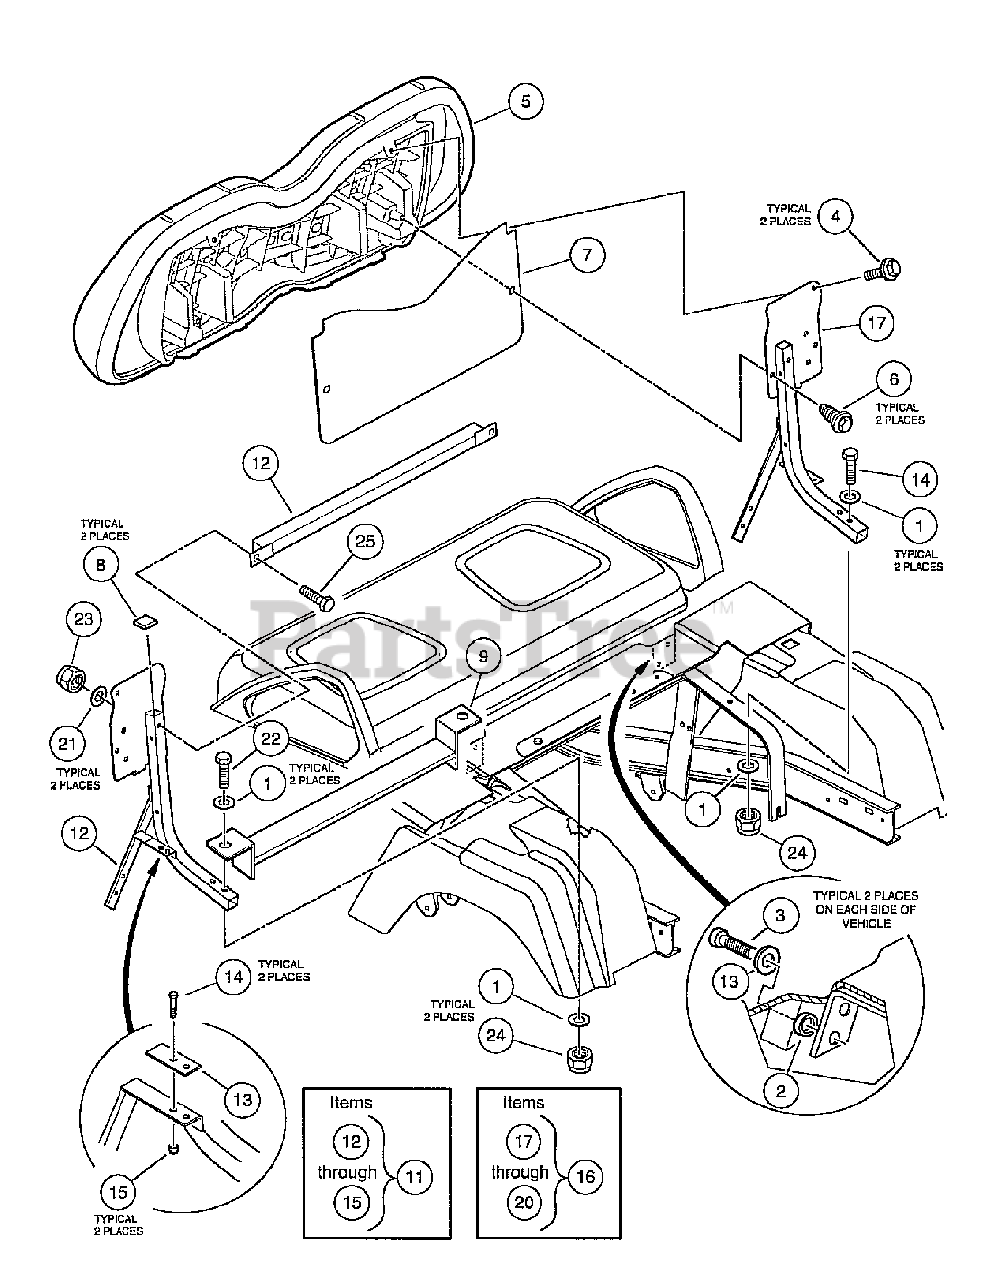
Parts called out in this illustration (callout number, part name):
1	Washer, 1/4 Flat
2	Body Spacer
3	Screw, 5/16-18 X 1.25 Thrd Frm
4	Screw - M6 X 1.0 X 30 Sems
5	Backrest Assembly, Gray
6	Screw, M6 Hex
7	Backrest Cover Plate
8	Plug, Square - 25.4 mm
9	Weldment, Bed Support
10	Seat Support, Cross Brace
11	Support, Seat, Left (driver)
12	Seat Support, Driver-Side
13	Plate, Bed Latch Striker
14	Screw, 1/4-20 X 0.75 Hex-Head Cap
15	Locknut, 1/4-20 Nylon Insert
16	Support, Seat, Right (passenger)
17	Seat Support, Passenger-Side
18	Plate, Bed Latch Striker
19	Screw, 1/4-20 X 0.75 Hex-Head Cap
20	Locknut, 1/4-20 Nylon Insert
21	Washer, 5/16 Type A Flat
22	Screw, 1/4-20 X 2.00 Hx Hd Cap
23	Locknut, 5/16-18 Nylon Insert
24	Locknut, 1/4-20 Nylon Insert
25	Screw, 5/16-18 X 1.75 Hex-Head Cap
